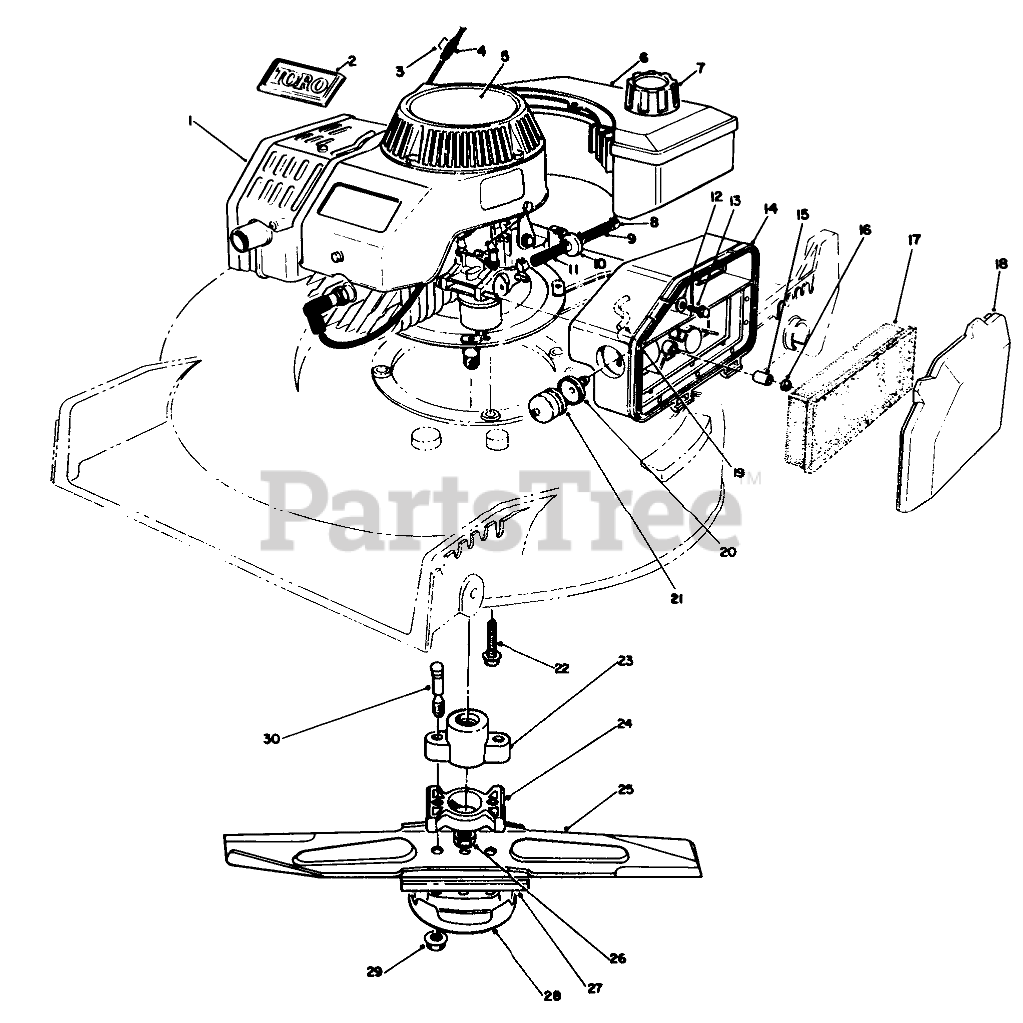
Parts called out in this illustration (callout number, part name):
1	Engine (Complete)
2	TORO LOGO PLT
3	Staple
5	DECAL - 2 CYC RECOIL
6	Gas Tank Assembly
7	GAS CAP ASM
8	CLAMP-FUEL LINE
9	HOSE-FUEL
10	FILTER-FUEL
11	HOSE-FUEL
12	WASHER-FLAT
13	SCREW-HH
14	BODY-AIR CLEANER
15	SPACER
17	ELEMENT-AIR CLEANER
18	COVER-AIR CLEANER
19	HOSE-PRIMER
20	BODY-PRIMER
21	BULB-PRIMER
22	SCREW-HHF
24	SPACER-BLADE
25	Blade-21" (Incl. Ref. #27)
26	NUT-LOCK, NI
27	Stiffener
28	CUP-SCALP, ANTI
29	NUT-LOCK
30	BOLT-BLADE
